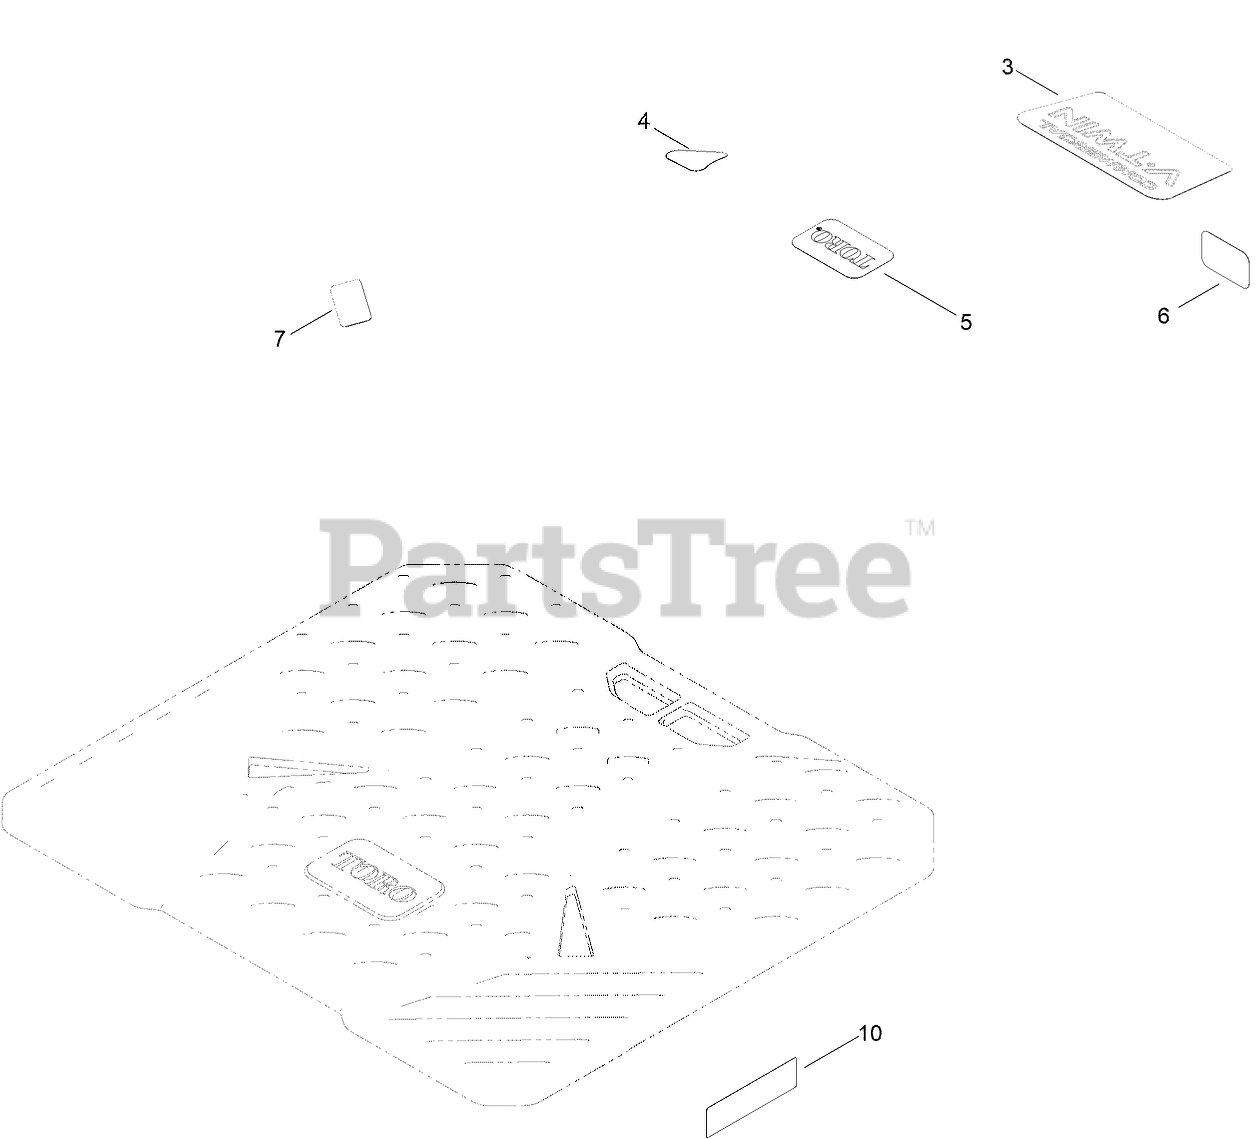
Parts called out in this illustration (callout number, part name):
3	DECAL-ENGINE
4	DECAL-DRAIN, OIL
6	PLACARD-INTAKE
7	DECAL-SHUTDOWN, CE
